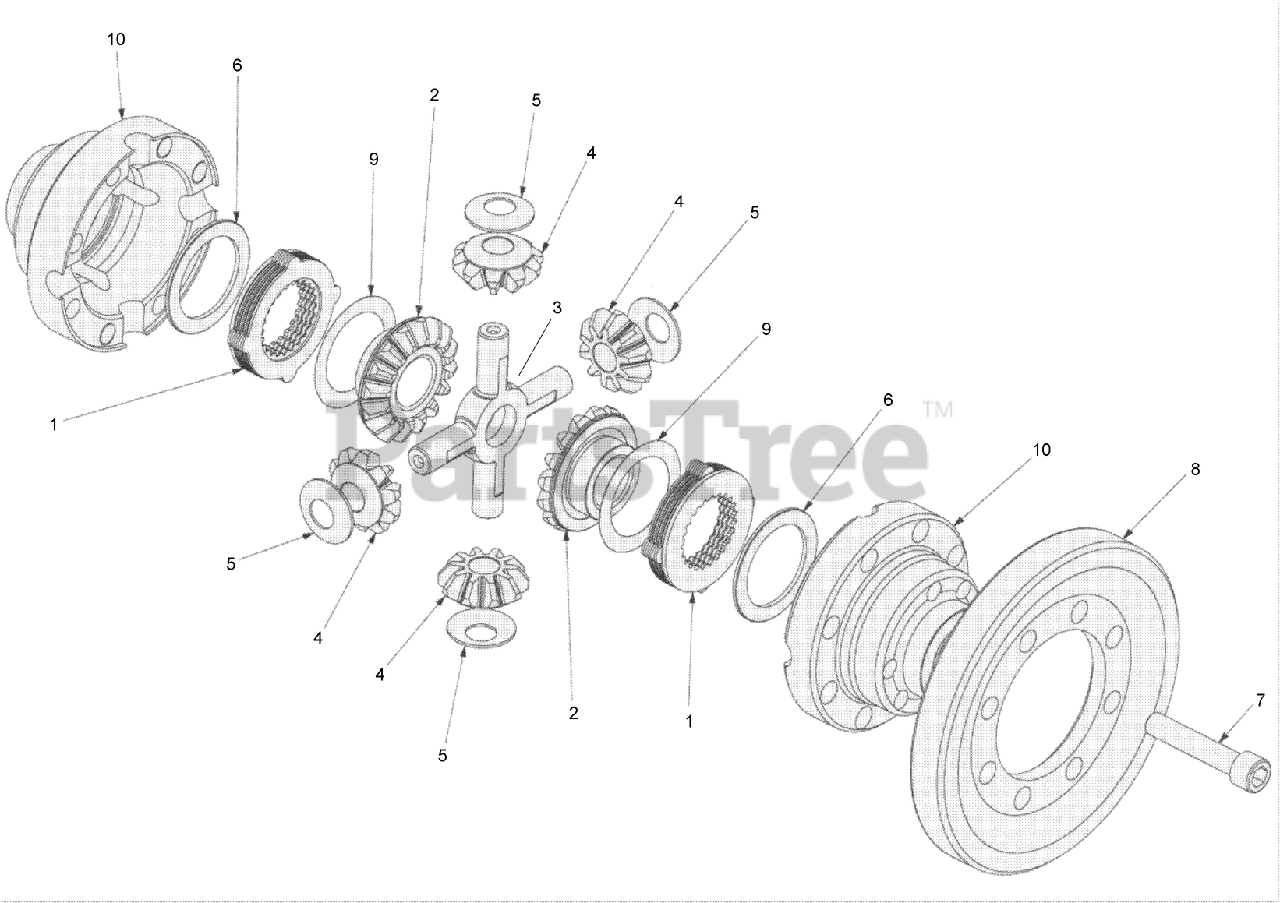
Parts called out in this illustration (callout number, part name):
1	PACKAGE-Disk
2	WHEEL-Crown
3	GEAR-Spider
4	PINION-Side
5	SHIM-Side Pinion
6	WASHER-Pinion
10	HOUSING-Differential
